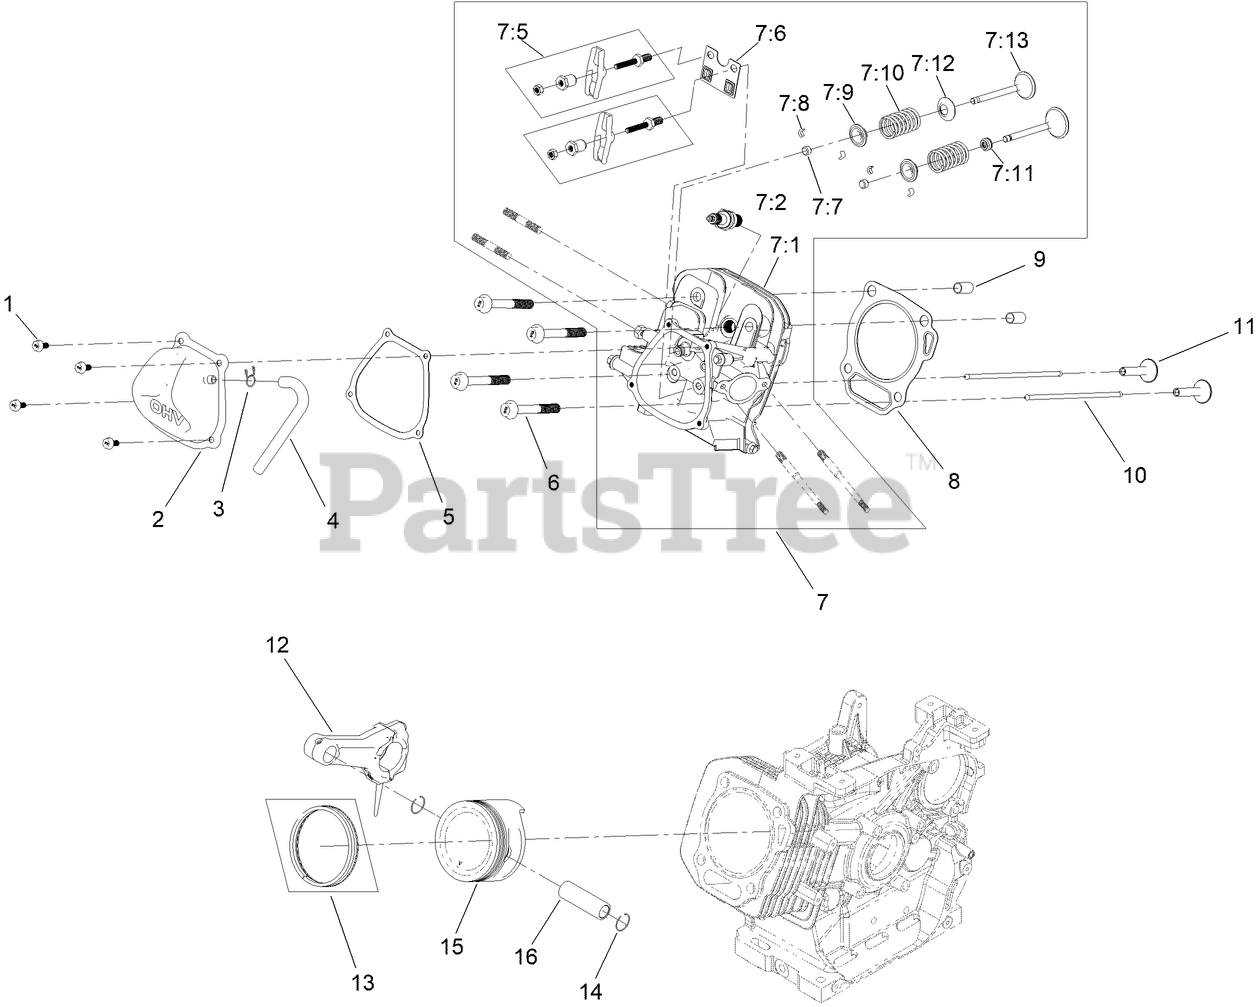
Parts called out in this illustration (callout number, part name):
1	SCREW-HHF
2	VALVE COVER ASM
3	CLAMP-HOSE
4	TUBE-BREATHER
5	GASKET-COVER, VALVE
6	SCREW-HHF
7	COMPLETE HEAD ASM
7:1	HEAD-CYLINDER
7:2	SPARK PLUG
7:5	ROCKER ARM ASM
7:6	PLATE-GUIDE, PUSH ROD
7:7	ROTATOR-VALVE
7:8	KEEPER-VALVE
7:9	RETAINER-SPRING, VALVE
7:10	SPRING-VALVE
7:11	SEAL-STEM, VALVE
7:12	SEAT-SPRING, VALVE
7:13	VALVE SET
8	GASKET-HEAD, CYLINDER
9	PIN-DOWEL
10	ROD-PUSH
11	LIFTER-VALVE
12	CONNECTING ROD ASM
13	RING SET
14	RING-RETAINING, PISTON PIN
15	PISTON
16	PIN-PISTON
